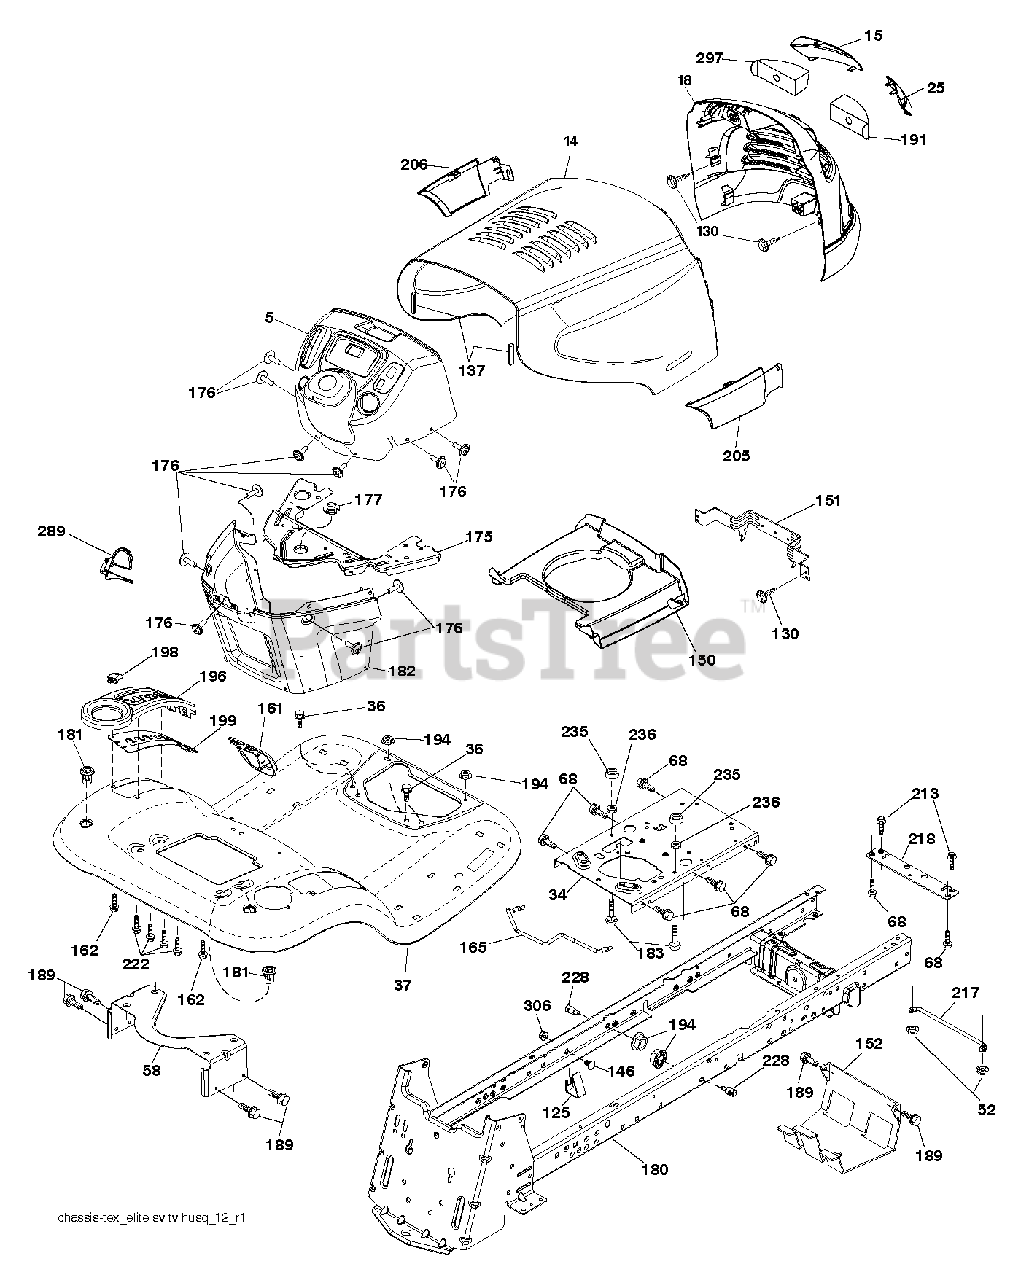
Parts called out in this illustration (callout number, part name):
14	HOOD.PNT.ELITE.TVENT.SVENT.SSK
18	GRILLE.ELITE HUSQ.BLACK.DL.
34	PLATE.ENGINE.WELDED.CHASSIS
36	SCREW 5/16"
52	LOCKNUT
58	BRKT.SUPPORT.FNDR/TANK
68	SCREW LT
125	CLIP.FUEL.LINE
130	SCREW.#10 X 0.750.BOS (2 2)
137	BUMPER.HOOD.LARGE.1.75"
146	BOLT.RDHD.SHT.SQNK.3/8-16X5/8
150	AIR DUCT
151	BRACKET PIVOT
152	SHIELD.BROWNING.W/TEX
161	CONSOLE.FUEL.WINDOW.STGT.BLACK
162	SCREW.HI-LO.CONSOLE
165	SUPPORT.TANK.REAR.W/TEX
175	CROSSMEMBER.LT
176	SCREW.#10-24X5/8.RN.QU
177	BUSHING,STEERING
180	CHASSIS.GT.SLOPED.DRAWBAR.
181	FEND/FTRST.PCH.CPH.NFW
182	DASH.LOWER.LT.CCS
183	BOLT.5/16-18X1-1/4 FULL THD
189	SCREW
191	INSERT.REFLECTIVE.RH.
194	NUT LOCK HEX FLANGE 5/16-18
198	INDICATOR.DECK.LIFT.RED
199	PLATE DECK LIFT
205	SKIRT.SIDE.RH.ELITE.HUSQ.428
206	SKIRT.SIDE.LH.ELITE.HUSQ.BLACK
213	BOLT
217	ROD.PIVOT.HOOD
218	X-PIECE.HOOD.STOP.NON/
222	SCREW.1/4-20X5/8
228	STUD.FASTNER.W/ANTI-ROTATE
235	SPACER FENDER
236	NUT.CENTERLOCK.5/16-
289	PLUG CRUISE HOOK PHONE
297	INSERT LENS
306	NUT LOCK FLG 3/8-16 UNC
